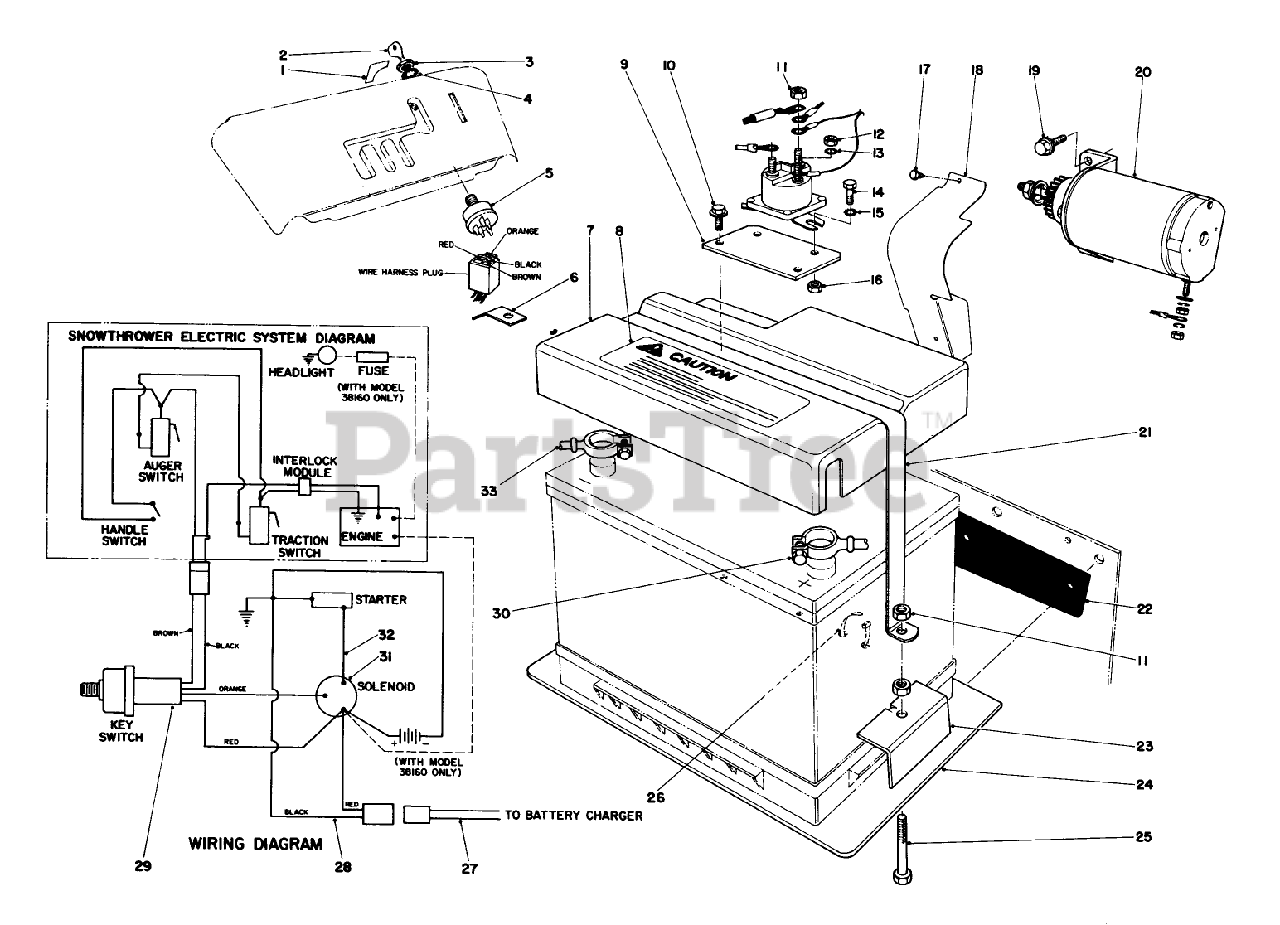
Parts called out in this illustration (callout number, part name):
3	NUT-HH
4	WASHER-LOCK
8	Decal-Caution
10	SCREW-HWH
11	NUT-HEX
12	NUT-HEX
13	WASHER-LOCK, INT
14	SCREW-HH
15	WASHER-LOCK/EXT
16	NUT-LOCK, NI
18	BRIGGS 280265
19	5/16-18X3/4 HX HD SEM
20	Starter Motor Pinion Assy.
25	SCREW-HH
26	TIE-CABLE
27	MALE WIRE ASM
30	BATT-SOLENOID CABLE
31	SOLENOID
